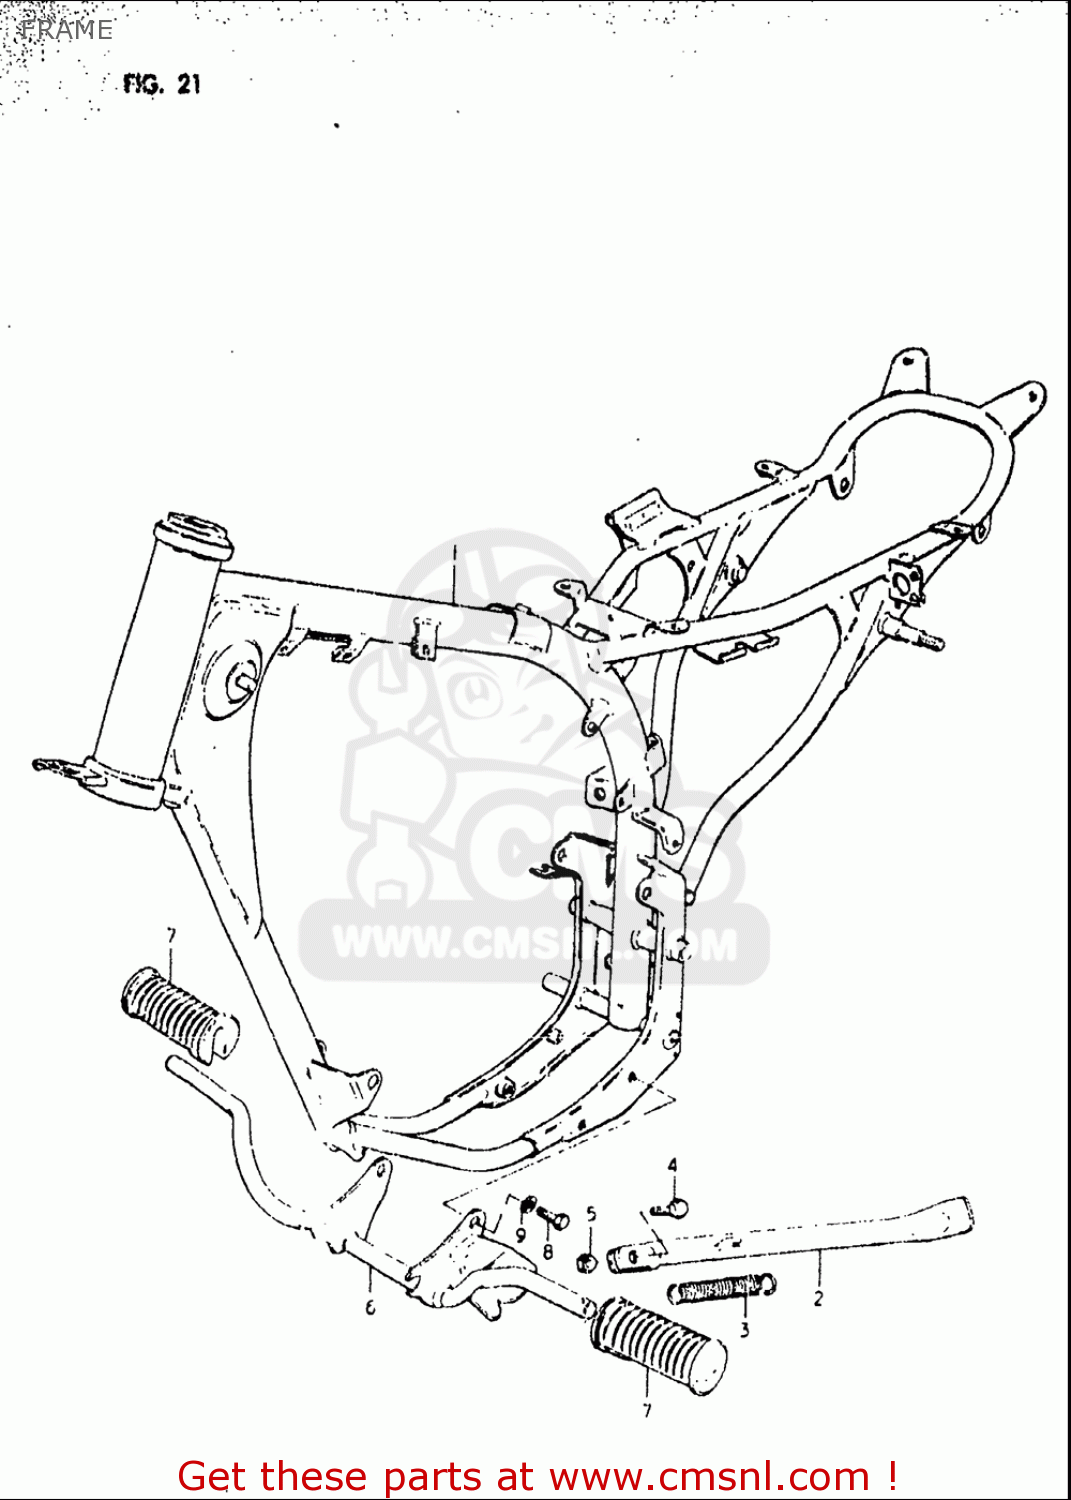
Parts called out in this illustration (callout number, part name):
3	SPRING
4	BOLT(10X27)
5	NUT
7	RUBBER,FR FOOTREST
8	BOLT
9	WASHER,LOCK
